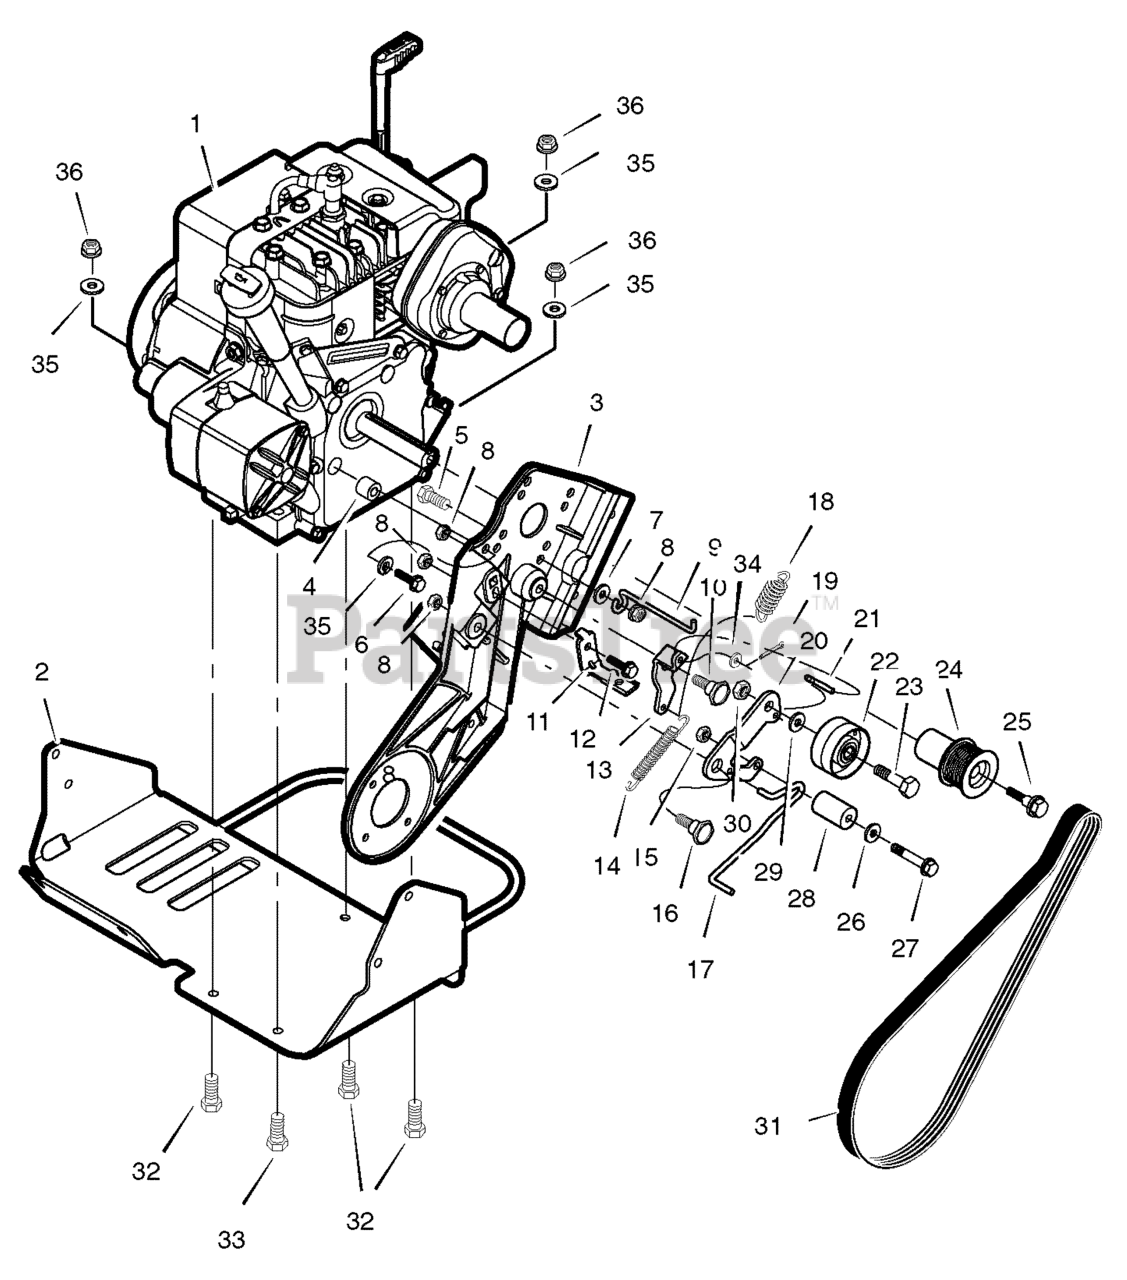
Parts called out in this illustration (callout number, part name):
1	Engine
2	Cradle Assy, Engine
3	Frame, Left
4	Mount, Antivibration
5	Bolt 5/16-18x 0865
6	Bolt 5/16-24x1.125
7	Washer, Flat
8	Locknut 5/16-18
9	Guide, Belt
10	Bolt
11	Pad, Brake
12	Screw, 1/4-20 x .63
13	Idler, Arm Pivot
14	Spring
15	Nut Hex 1/4-20
16	Bolt
17	Wire, Brake
18	Spring
19	Pin, Cotter
20	Arm, Idler
21	Rod, Clutch Linkage
22	Pulley, Idler
23	Screw, 3/8-16 x 1.50
24	Pulley, Engine
25	Bolt, Engine Pulley
26	Washer, Flat
27	Screw, 1/4-20 x 2.00
28	Pinch Roller
29	Washer, Flat
30	Nut, Hex
31	Belt, Drive
32	Bolt, Hex 5/16-18X1.625
33	Screw 3/8-16X1.00
34	Washer, Flat
35	Lockwasher, Split
36	Nut 5/16-18
